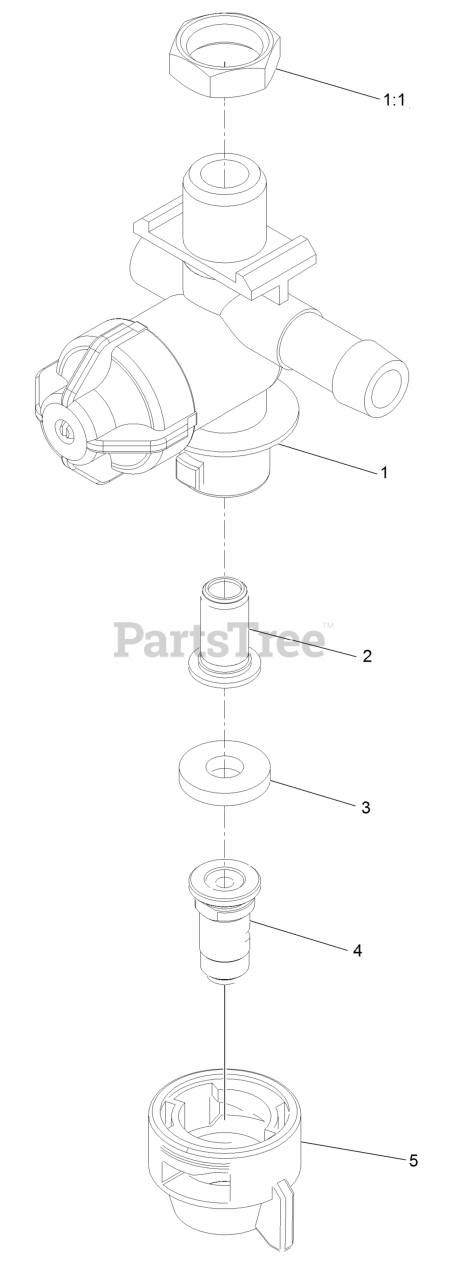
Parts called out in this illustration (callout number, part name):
1	LH NOZZLE BODY ASM
1:1	NUT-NYLON
2	STRAINER-TIP
4	NOZZLE-SPRAY, WHITE
5	CAP-NOZZLE
